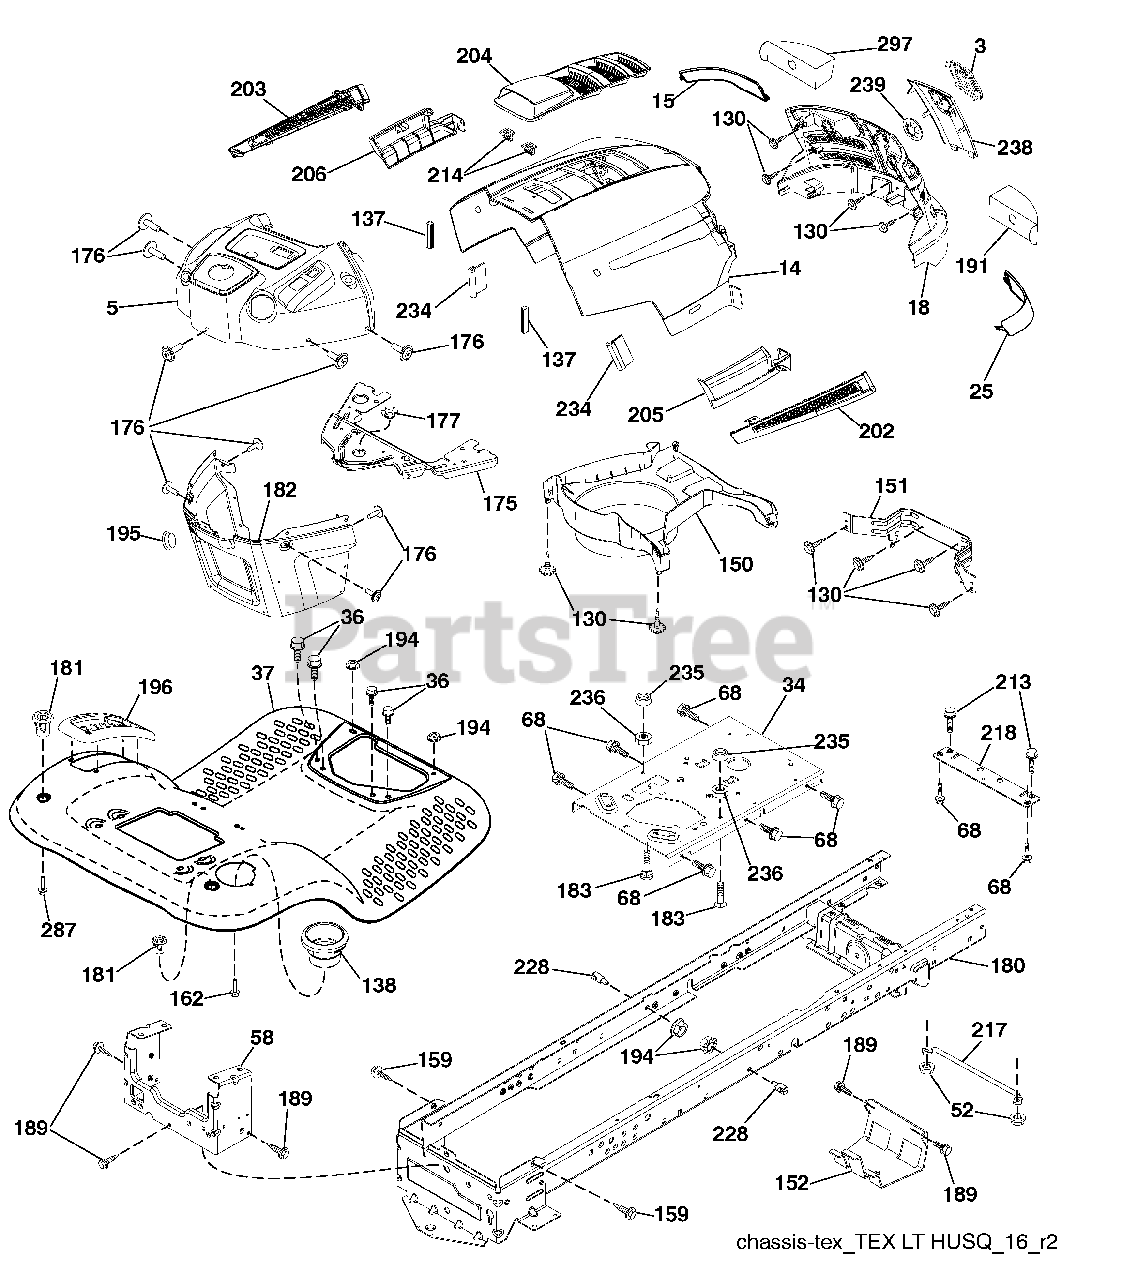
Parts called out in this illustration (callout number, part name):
3	Logo
5	Dash
14	Hood
15	Lens LH
18	Grille
25	Lens RH
34	Plate Engine
36	Screw 5/16-18 x 3/4
37	Fender
52	Nut Crown Lock 5/16
58	Drawbar Upper
68	Screw THDROL 5/16-18 x 1/2
130	Screw #10 x 0.750 BOS Thread
137	Bumper Dash
138	Cupholder
151	Bracket Pivot
152	Shield Browning
159	Screw Hexwash Thor 3/8-16 x 3/4
175	Crossmember Plate
176	Screw 10-24 x 5/8
177	Bushing Steering
181	Bushing Mtg. Fender Crgo
182	Dash Lower
183	Bolt 5/16-18 x 1-1/4 Full Thd
189	Screw 5/16-18 x 3/4
191	Insert Reflective RH
194	Nut Lock Hex Flange 5/16-18
195	Plug Dash
196	Console Asm. Deck Lift
202	Vent Side Hood RH
203	Vent Side Hood LH
204	Vent Top Hood
205	Skirt Side RH
206	Skirt Side LH
213	Bolt 5/16-18 x 3/4
214	Clip Retainer
217	Rod Pivot Hood
218	X-Piece Hood Stop
228	Stud Fastener
234	Bumper Hood
235	Spacer Fender
236	Nut Lock 5/16-18 unc
238	Trim
239	Clip Tinnerman
287	Screw Hex Washead 1/4-20 x 3/8
297	Insert reflective LH
